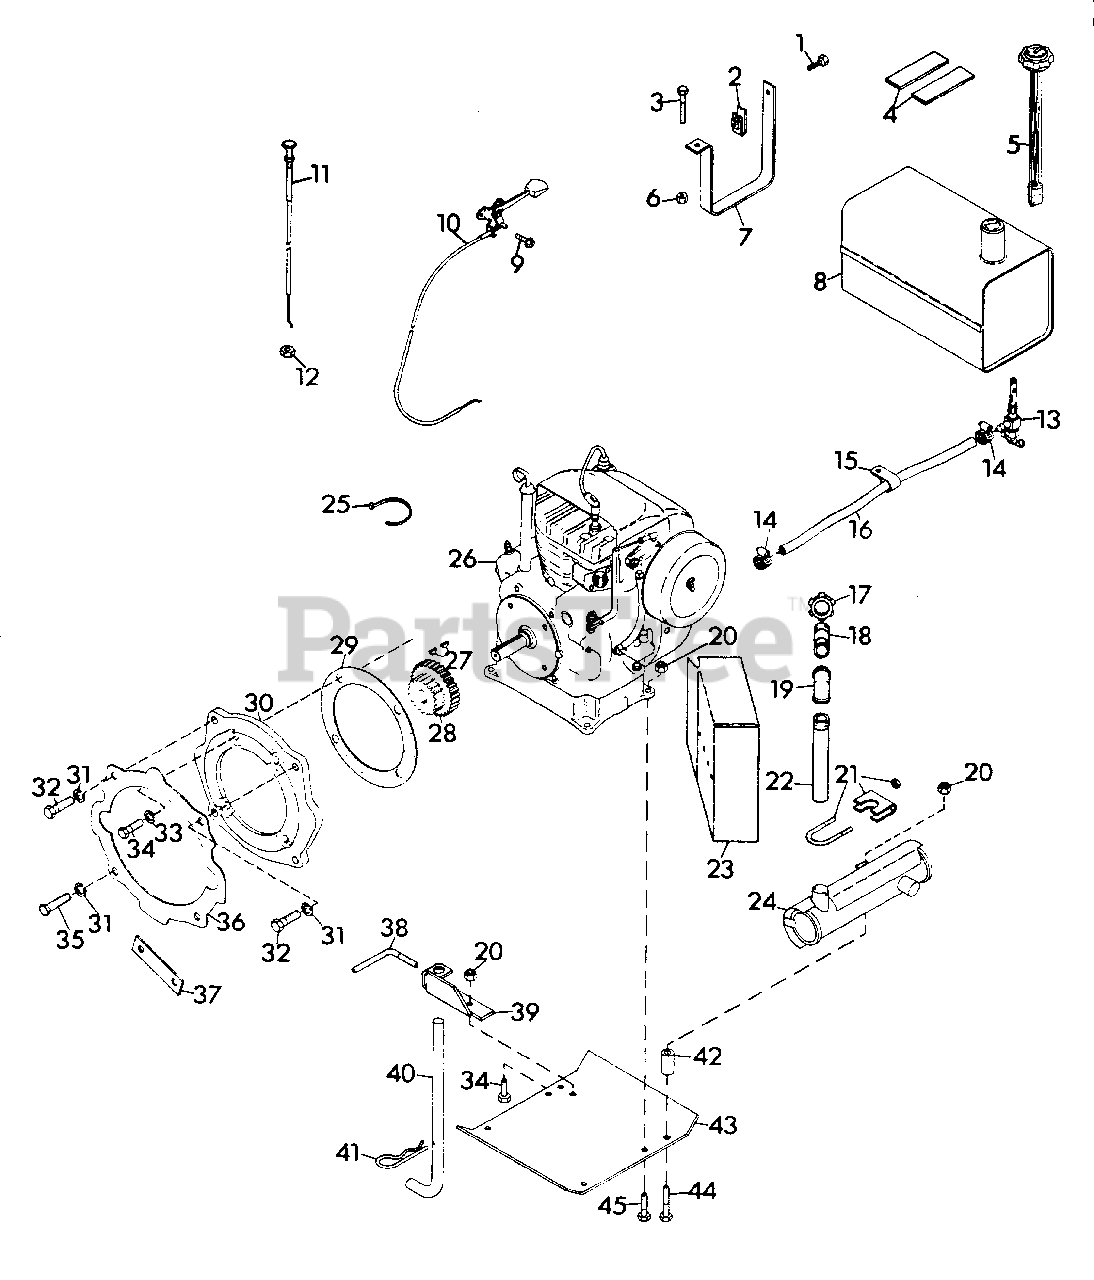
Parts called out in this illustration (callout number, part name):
1	BOLT, HEX 5/16-18X.75
2	NUT, RETAINER
3	BOLT, HEX 5/16-18X1.25
4	PAD, GAS TANK
5	GAUGE, FUEL
6	NUT, LOCK 5/16-18
7	STRAP, GAS TANK
8	TANK, FUEL
9	SCREW, TAPPING 10-24X.50
10	LEVER, CONTROL
11	CONTROL, CHOKE
12	NUT, JAM 3/8-24 HEX
13	VALVE AND STRAINER
14	CLAMP, HOSE
15	CLAMP, NYLON
16	LINE, FUEL
17	NUT, CONDUIT 1.25" PIPE
18	NIPPLE, 1.25 PIPE
19	ELBOW, 1.25 PIPE
20	NUT, LOCK 3/8-16
21	CLAMP, MUFFLER
22	NIPPLE, 1.25 PIPE 7.8 LG
23	SHIELD, HEAT
24	MUFFLER, KOHLER 16-HP
25	TIE, CABLE
26	ENGINE, 16-HP PRO MASTER-50
27	KEY, WOODRUFF 5/32X.625
28	GEAR, 10/12 DP 21/30 TEETH
29	GASKET, ENGINE TO ADAPTOR
30	ADAPTOR, ENGINE
31	WASHER, LOCK 7/16 SP HEAVY
32	BOLT, HEX 7/16-14X1.50
33	WASHER, LOCK 3/8 SP HEAVY
34	BOLT, HEX 3/8-16X1.00
35	BOLT, HEX 7/16-14X1.25
36	GASKET, CHASSIS TO ADAPTOR
37	STRAP
38	HANDLE, ADJUSTING
39	STAND, SUPPORT
40	STAND, KICK
41	PIN, HAIR
42	BUSHING, .407X.625X.812
43	PLATE, SKID
44	BOLT, HEX 3/8-16X1.75
45	BOLT, HEX 3/8-16X1.50
